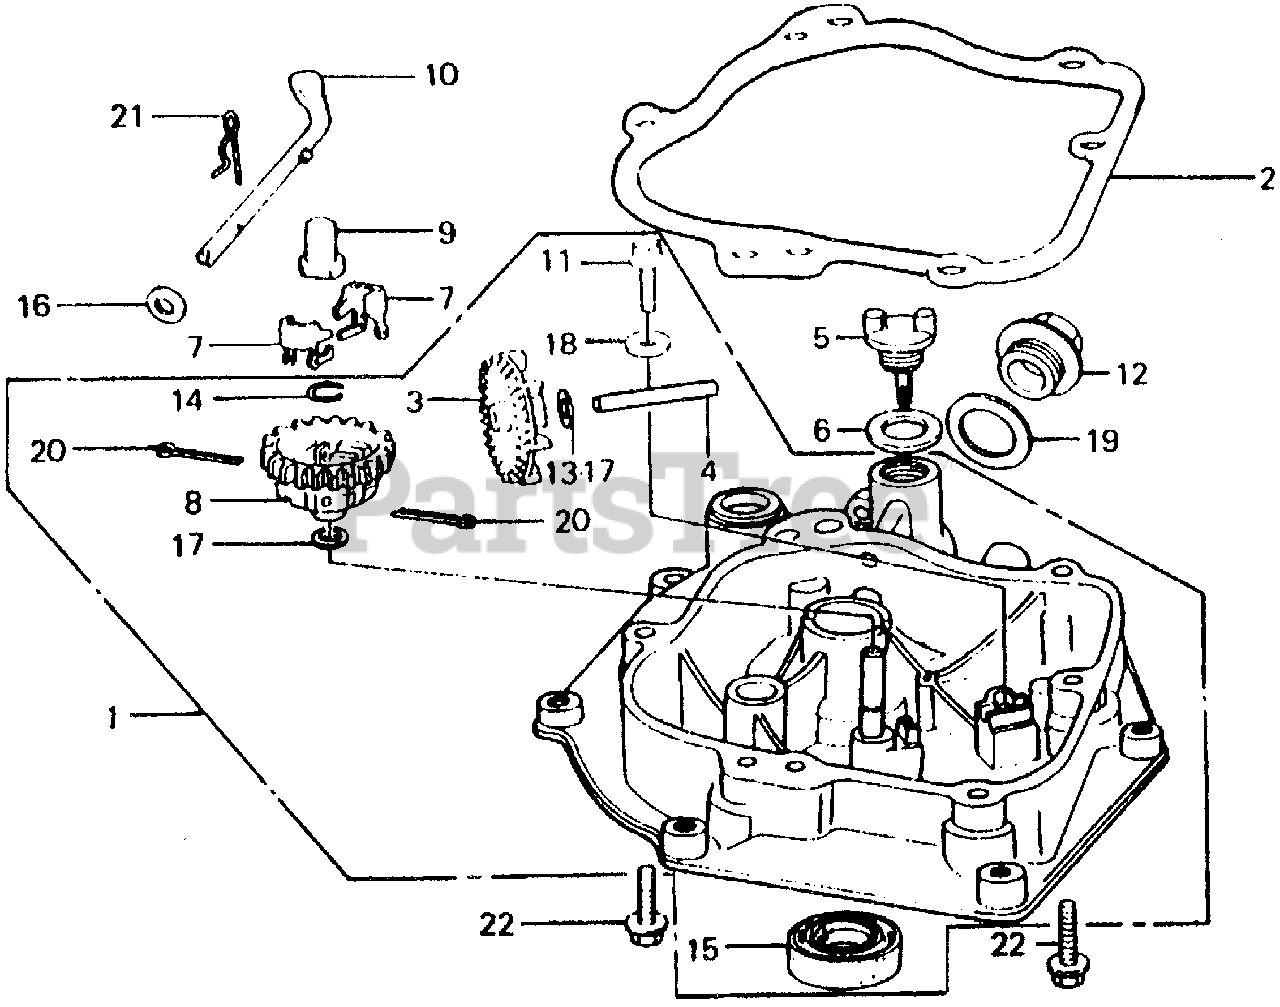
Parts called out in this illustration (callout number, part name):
1	PAN ASSY., OIL
2	GASKET, CASE COVER
3	SLINGER, OIL
4	SHAFT, OIL SLINGER
5	CAP, OIL FILLER (NOT AVAILABLE)
6	GASKET, OIL FILLER CAP
7	WEIGHT, GOVERNOR
8	HOLDER, GOVERNOR WEIGHT
8	HOLDER, GOVERNOR WEIGHT (NOT AVAILABLE)
9	SLIDER, GOVERNOR
10	SHAFT, GOVERNOR ARM
11	BOLT, FLANGE (5X16)
12	BOLT, DRAIN PLUG (20MM)
13	WASHER (6MM)
14	CLIP, GOVERNOR HOLDER
15	OIL SEAL (20X34X6)
16	WASHER, PLAIN (5MM)
17	WASHER, PLAIN (6MM)
18	WASHER, PLAIN (5MM)
19	WASHER, DRAIN PLUG (20MM)
20	PIN, GOVERNOR WEIGHT
20	PIN, COTTER (2.5X28)
21	PIN, LOCK (8MM)
22	BOLT, FLANGE (6X28)
